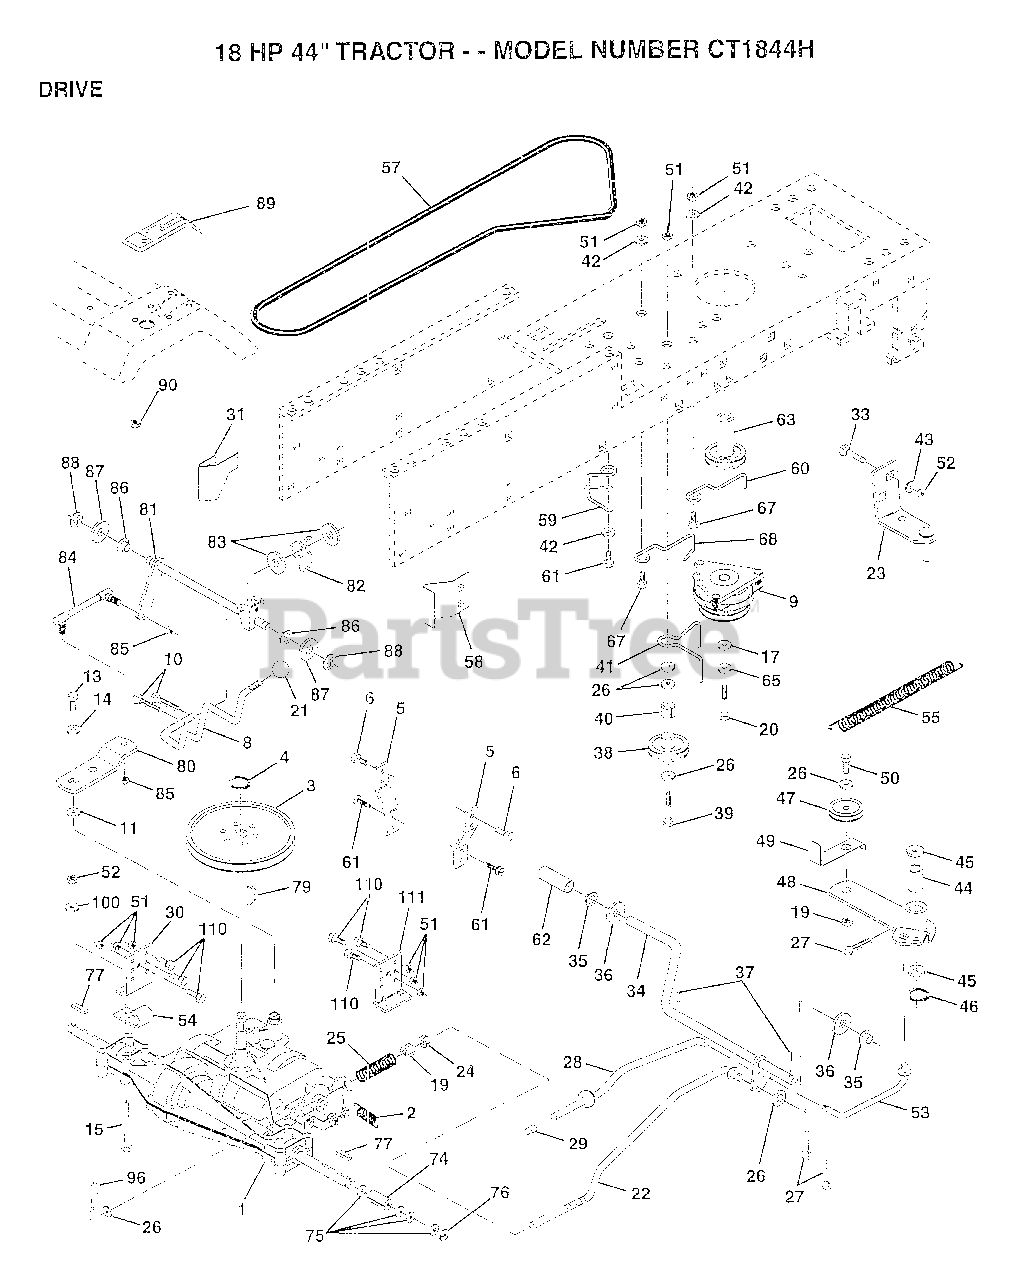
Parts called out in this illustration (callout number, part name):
1	TRANSAX. PRLES.
3	PULLEY TRANSAXLE
4	RING
5	STRAP TORQUE
6	SCREW
10	PIN COTTER 1/8
11	WASH-SHFT PLT LT
13	BOLT.1/4-28.W/PAT
14	WASHER PM
15	BOLT HEX
17	WASHER
19	NUT
21	CONTROL KNOB LT
22	ROD.ASM.BK.44.MWR
23	BRACKET.ASM.MTG
24	NUT
25	"SPRING,ROD BRAKE"
26	WASHER
27	COTTER PIN
28	BRAKE PARK ROD
30	BRKT TRANS LH
31	KEEPER BELT LH
33	BOLT
35	NYLON BEARING
36	WASHER LT
38	PULLEY.IDLER.FLAT
39	BOLT
40	SPACER T
41	BELT KEEPER LT
42	WASHER
43	WASHER T
44	"LY, BEARING"
45	WASHER LT
46	KLIP RING
48	ARM IDLER
49	RETAIN BELT
52	NUT
53	"LINK, CLUTCH T"
54	CLIP T
55	"SPRING, RETURN LT"
57	BELT.GRDRV.94.75
58	"KEEPER,BELT RH"
59	KEEPER BELT CNTSP
60	KEEPER BELT ENGLH
61	SCREW
62	PEDAL COVER T
63	PULLEY ENGINE
65	LOCKWASHER
67	BOLT
68	"KEEPER,BLT ENG LT"
74	SPACER HYT
75	WASHER
76	E RING HYT
77	SQ KEY STD
80	"ARM,SHIFT"
81	"SHAFT,SHIFTER"
82	"SPRING,TORSION"
83	WASHER
84	"ROD,TIE "
85	NUT 1/4-28
86	BUSHING
87	WASHER D
88	KLIP RING
89	CONSOLE SHIFTER
90	NUT
96	RETAINER M
100	WASHER M
111	BRKT TRANS RH
